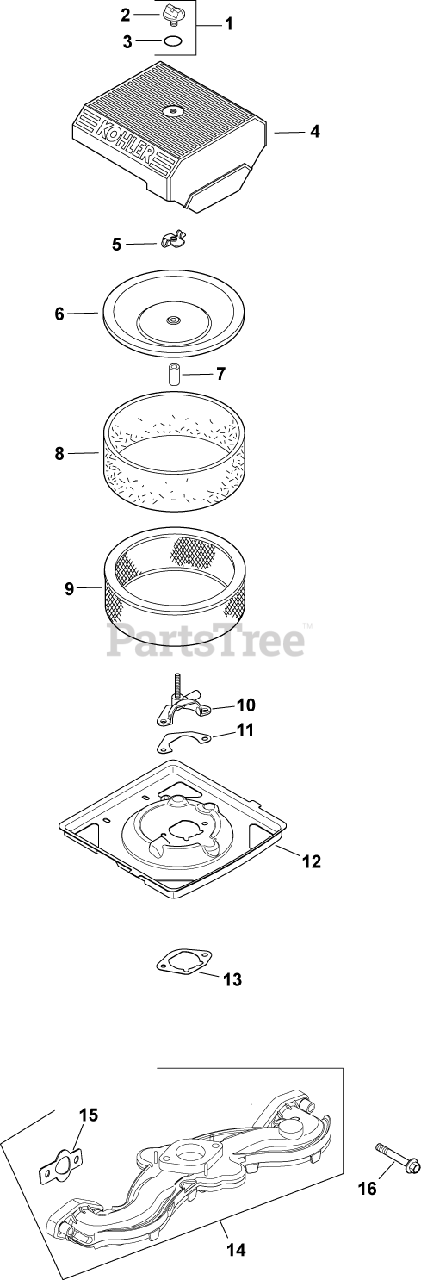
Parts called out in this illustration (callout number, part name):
1	KIT, KNOB W/SEAL
2	KNOB, COVER
4	COVER, AIR CLEANER
5	NUT, WING
6	COVER, INNER AIR CLEANER
7	SEAL, BREATHER
8	PRE-CLEANER (HIGH)
9	ELEMENT, AIR FILTER (HIGH) - Also available Retail Packaged 24 883 03-S1 Air Filter Kit
10	CUP, FUEL SPITBACK W/NIPPLE
11	GASKET, FUEL SPITBACK CUP
12	BASE, AIR CLEANER-USE 24 094 87-S
13	GASKET, AIR CLEANER BASE
14	MANIFOLD, INTAKE
15	GASKET, INTAKE MANIFOLD USE 24 041 79-S
16	SCREW, FLG M6X1.0X55
